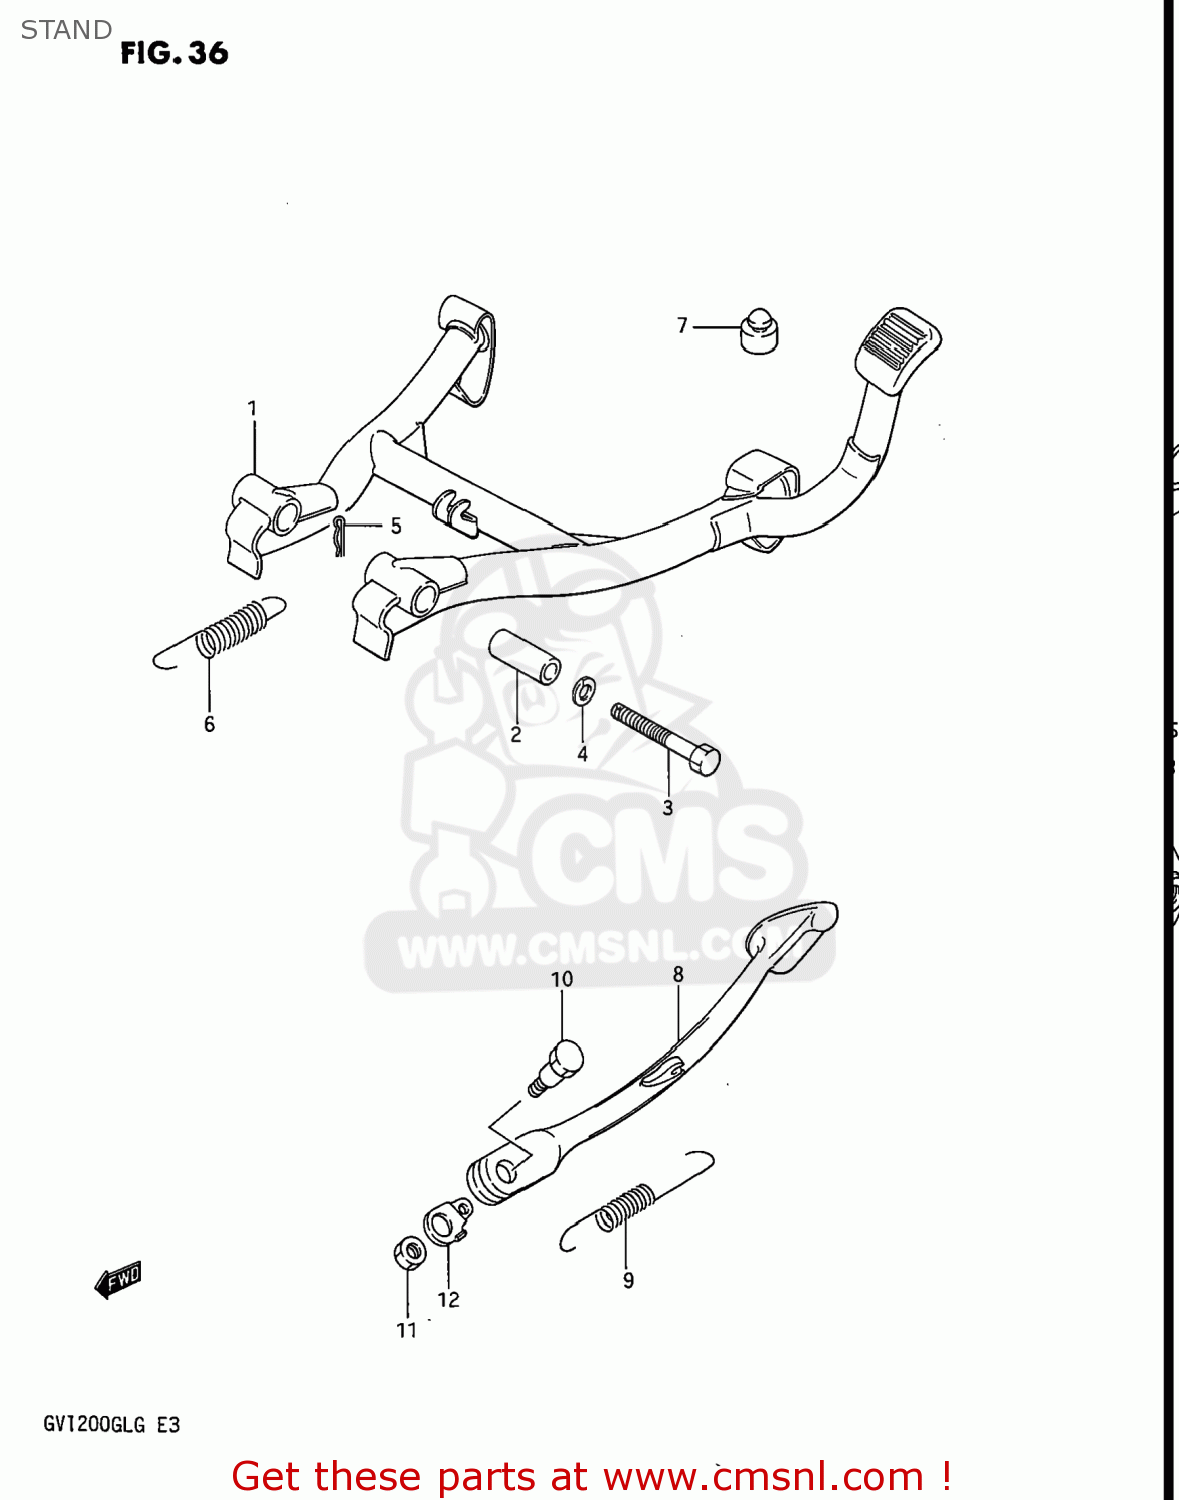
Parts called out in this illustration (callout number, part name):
1	STAND,CENTER
2	SPACER(10X16X38.8)
3	BOLT
4	WASHER,LOCK,10
5	CLIP
6	SPRING
7	CUSHION
8	STAND,SIDE
9	SPRING
10	BOLT(10X34)
11	NUT
12	PLATE,SIDE STAND WARNING
